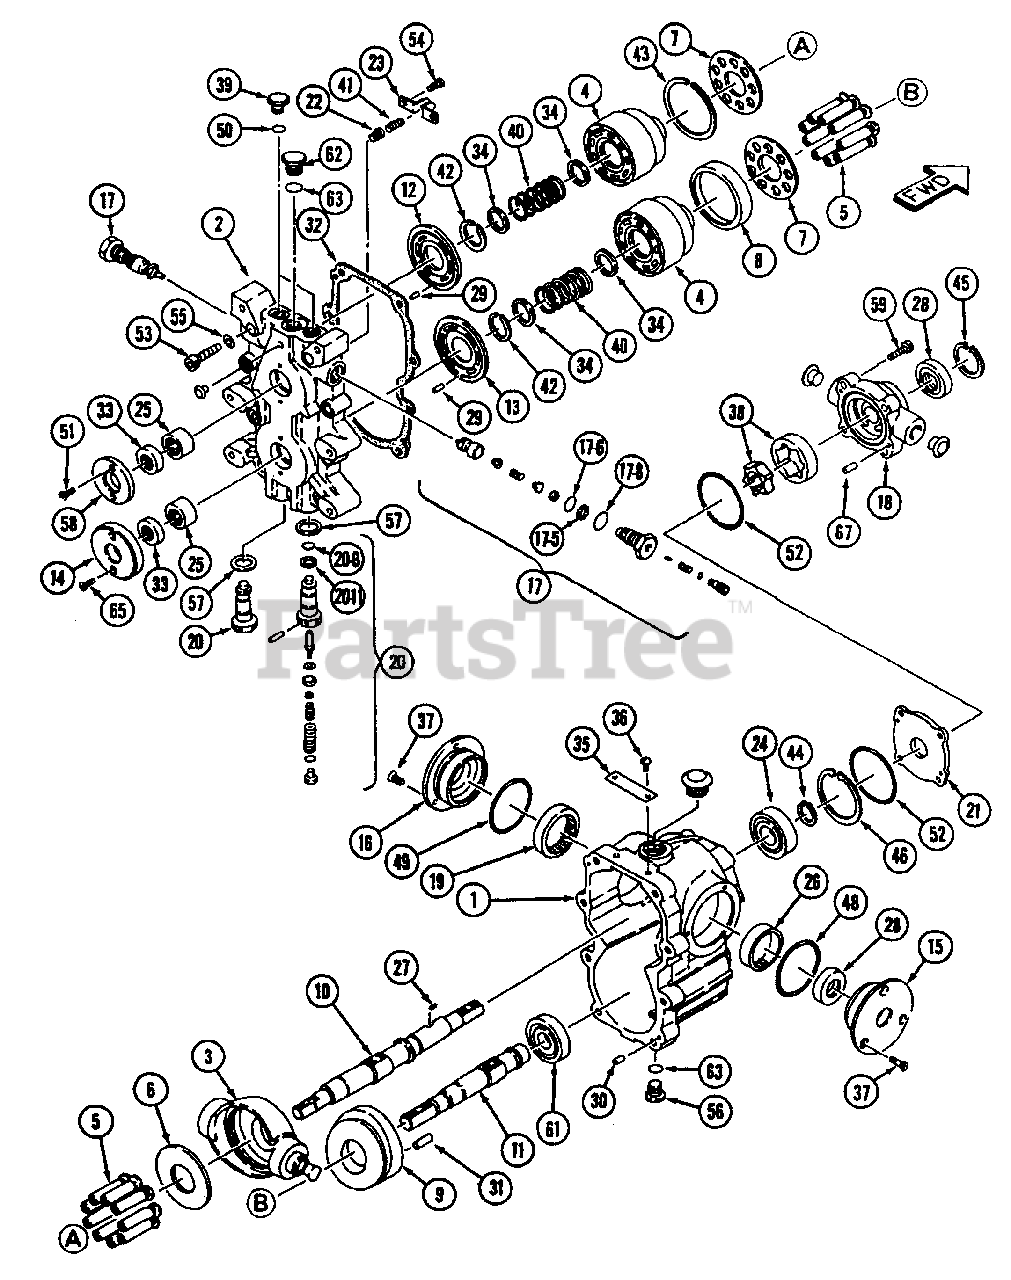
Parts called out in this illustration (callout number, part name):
4	Cylinder Block
5	Piston S/A
6	Plate, Thrust
7	Plate, Retainer
8	Holder, Retainer
9	Swash, Plate
15	Cover A
16	Cover B
18	Case,Change Pump
19	Bearing, Needle
20-11	Ring, Back Up
23	Holder, Spring
24	Bearing, Ball
25	Bearing, Needle
26	Bushing
34	Holder, Spring
35	Plate, Name
36	Screw, Drive
38	Trochoid Roto S/Ar
40	Spring
42	Ring, Snap
55	Washer, Spring
61	Bearing, Ball
